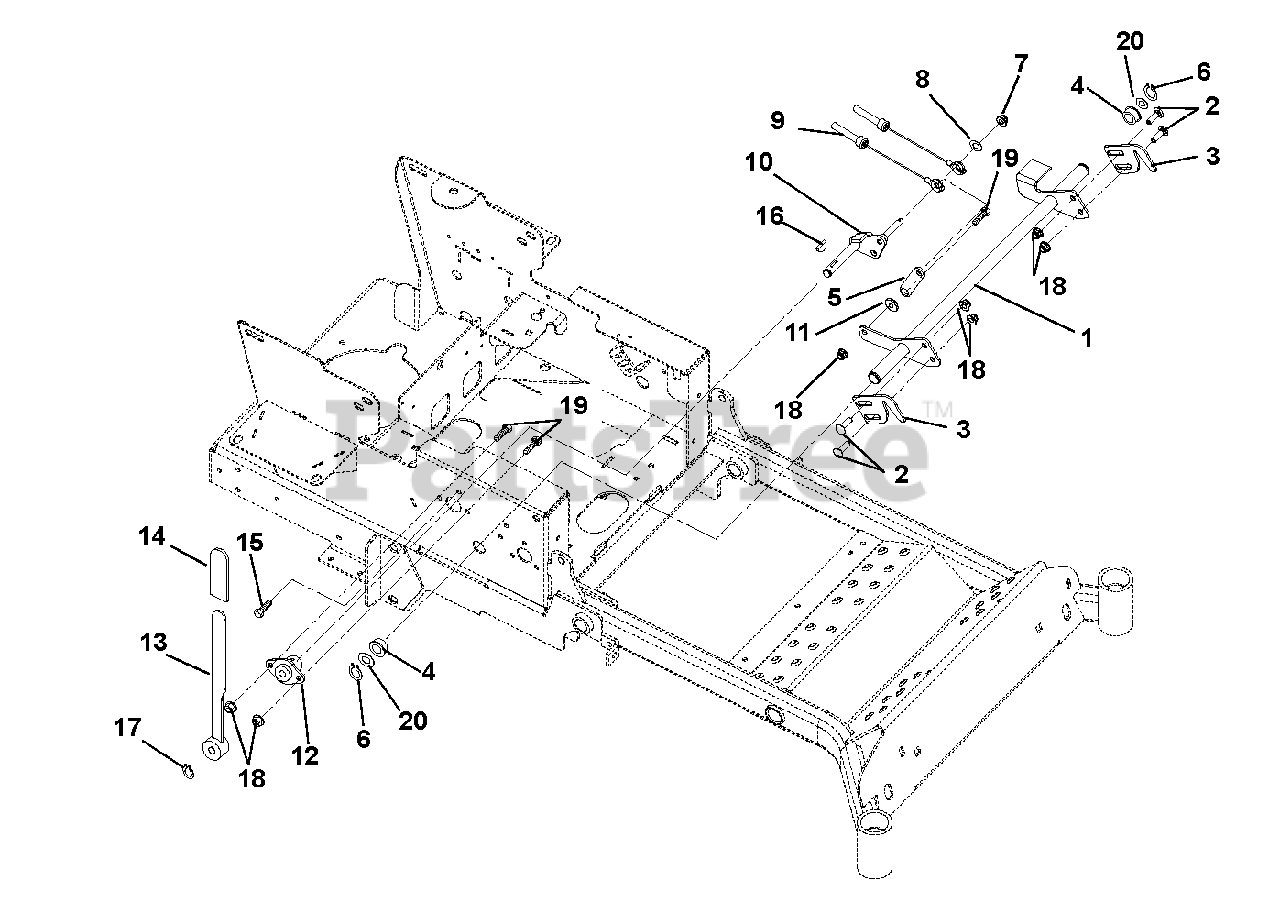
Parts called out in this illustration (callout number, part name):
1	Weldment, Neutral Lock Arm
2	Bolt, Round Head Square Neck .31-18 x 1.00 Grade 5
3	Neutral Lock Latch
4	Bushing, Flange .750 x 1.000 x .625 x 1.250
5	Plate, Neutral Interlock
6	Ring, Retaining, External .689 x .077
7	Nut, Push .312
8	Washer, Flat Steel .344 x .688 x .065
9	Cable, Brake Actuating
10	Weldment, Park Brake Arm
11	Bushing, Flange .325 x .499 x .26 x .88
12	Bushing, Flange
13	Weldment, Parking Brake Lever
14	Grip, Parking Brake
15	Screw, Tapping .38-16 x 1.00 Hex Washer Head
16	Key, Woodruff .13 x .63
17	Ring, Retaining External .50 x .05
18	Nut, Nyloc Flange 5/16-18
19	Bolt, Hex .31-18 x 1.00 Grade 5
20	Washer, Flat Steel .812 x 1.370 x .100
